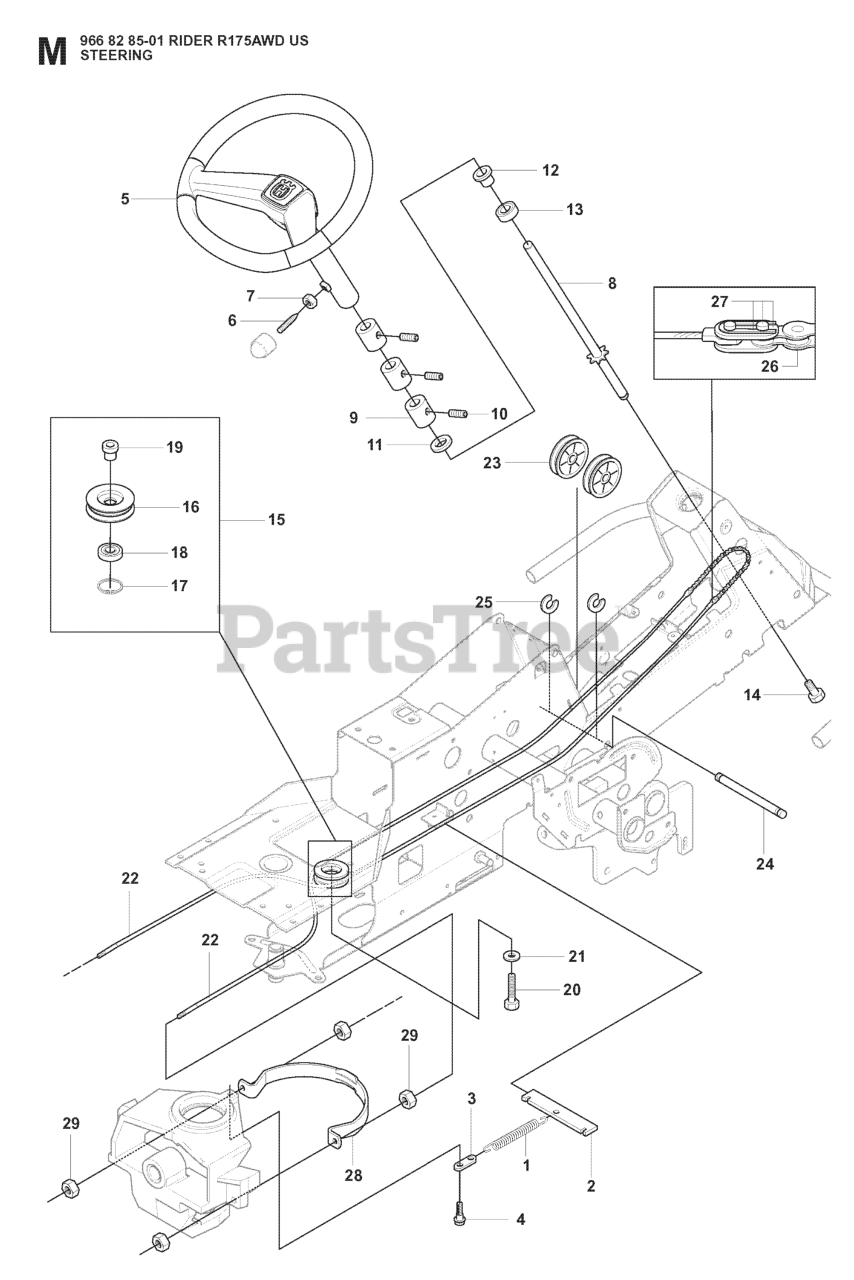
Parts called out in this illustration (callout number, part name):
2	SPRING BRACKET
5	STEERING WHEEL
7	NUT
8	ROD STEERING ASSY
9	SPACER
13	BALL BEARING 6004-2RS1
17	CIRCLIP SGH 47
18	BALL-BEARING 6204-2RS
22	RP STEERING CABLE COMPLETE
25	RETAINING RING
26	STEERING CHAIN
28	WIRE GUIDE
29	NUT
